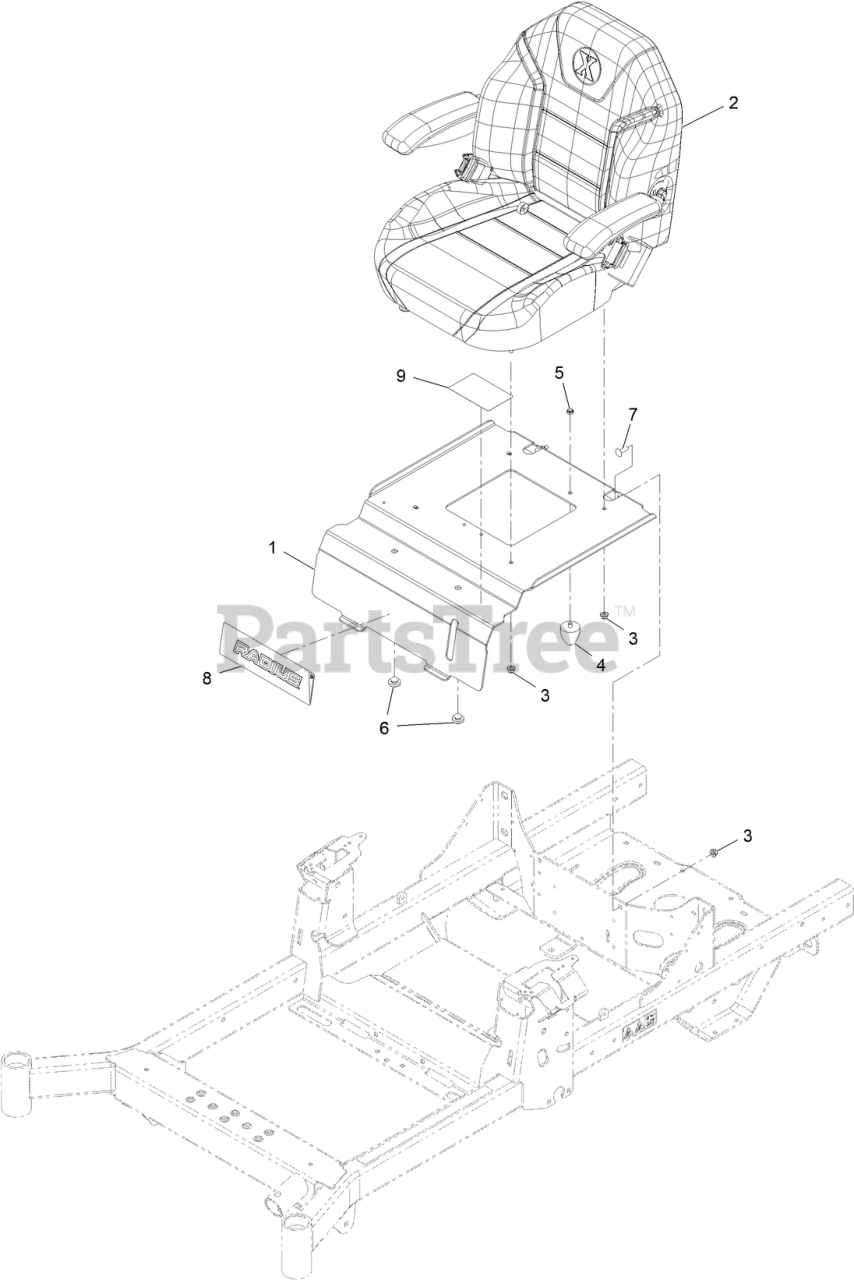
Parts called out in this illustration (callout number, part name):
1	Support, Seat
3	NUT-HF, NI
4	BUMPER-RUBBER
5	NUT-LOCK, NI
6	BUMPER-SEAT
7	SCREW-CARR
8	DECAL-RADIUS LOGO
9	DECAL-SERVICE AID
